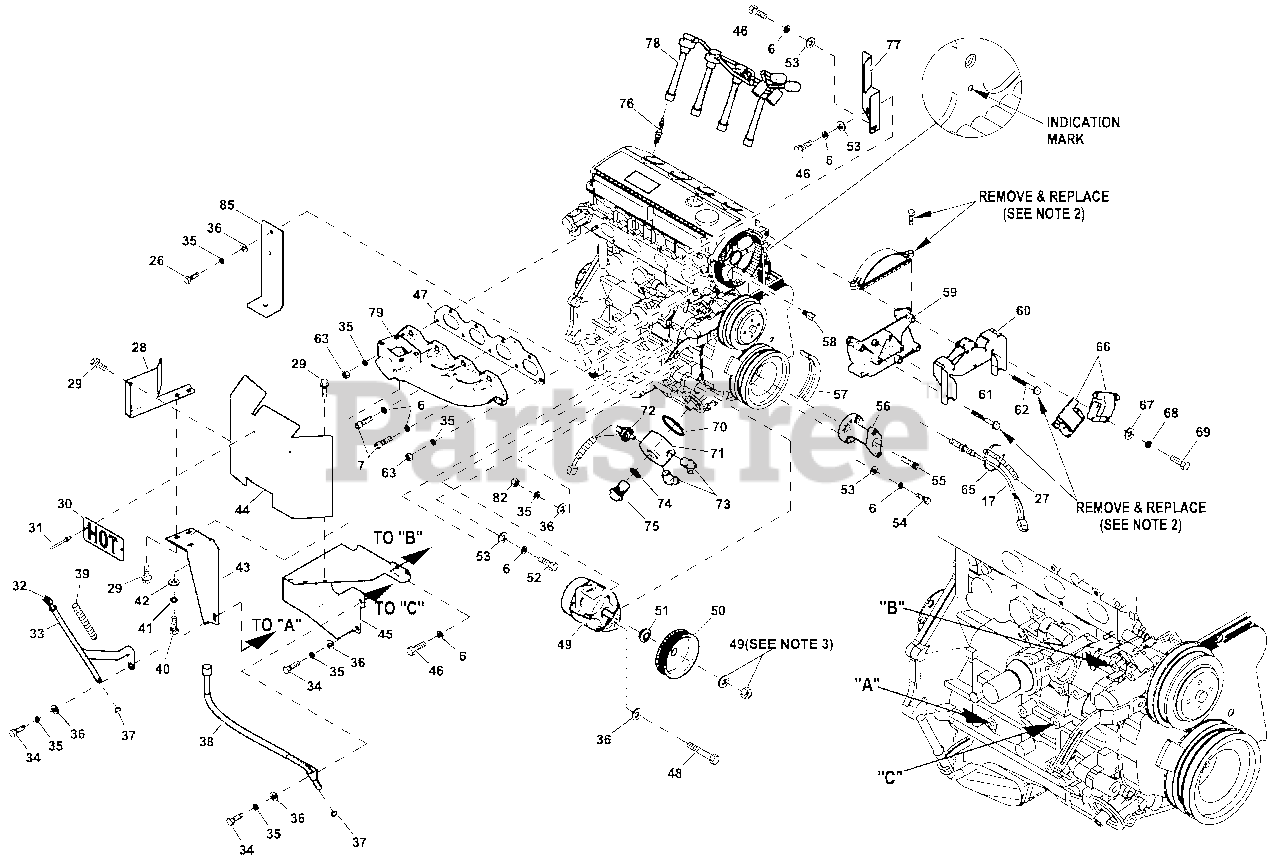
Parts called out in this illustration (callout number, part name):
1	ENGINE 2.4LG2 CERTIFIED
2	CLAMP HOSE #6 .43-.78
3	HOSE 5/16 ID TYP1SNGL HTR
4	GASKET INTAKE MANIFOLD G2
5	MANIFOLD INTAKE (MACHINED)
6	WASHER LOCK M8-5/16
7	SCREW SHC M8 -1.25 X 25
8	TEMPERATURE SENDER, DELPHI
9	PLUG STD PIPE 1/4 STEEL SQ HD
10	NUT HEX M8-1.25 G8 CLEAR ZINC
11	WASHER NYLON .565
12	TUBE OIL FITTING ASSEMBLY
13	SCREW HHCM10-1.25X40 C8.8
14	DECAL G2 IMPORT
15	NUT HEX M6-1.0 G8 CLEAR ZINC
16	SCREW SHC M8-1.25 X 30 C12.9
17	MAGNETIC PICKUP
18	MOTOR STARTER
19	SPACER 2.4L G2 FLEX PLATE
20	ADAPTER ENGINE
21	FLEX PLATE 2 POLE 2.4L G2
22	WASHER FLAT .531 ID X 1.062 OD
23	SCREW HHCM12-1.25X 20 C10.9
24	SCREW HHCM10-1.25X45 G8.8
25	WASHER SHAKEPROOF EXT 7/16 STL
26	SCREW HHCM10-1.25X30 G8.8
27	CONDUIT FLEX.25"ID(7.5"LG)
28	SHIELD INNER HEAT 2.4L TURBO
29	SCREW HHTT M6-1.0 X 12 ZINC
30	PLATE "HOT"
31	RIVET POP .125X0.337 STEEL
32	ASSEMBLY DIPSTICK G2.4L
33	ASSY DIPSTICK TUBE 2.4 G2
34	SCREW HHCM10-1.25X 20 C8.8
35	WASHER LOCK M10
36	WASHER FLAT 3/8-M10 ZINC
37	O-RING SIZE 9.0MM X 2.0MM NITR
38	TUBE TURBO OIL RETURN G2 2.4L
39	CONDUIT THERMAL FLEX 13MM ID
40	SCREW HHC M6-1.0 X 16 C8.8
41	WASHER LOCK M6-1/4
42	WASHER FLAT 1/4-M6 ZINC
43	BRACKET EXH MANIFOLD 2.4 TURBO
44	HEAT SHIELD TURBO 2.4L
45	BRACKET HEAT SHIELD 2.4L
46	SCREW HHC M8-1.25X 16 C8.8
47	GASKET EXHAUST MANIFOLD
48	SCREW HHC M10-1.5X 120 C8.8
49	ALTERNATOR DC W/OUT PULLEY
50	PULLEY DC ALTERNATOR
51	SPACER DC ALTERNATOR PULLEY
52	SCREW HHC M8-1.25X 25 G10.9
53	WASHER FLAT 5/16-M8 ZINC
54	SCREW HHC M8-1.25X35 G8.8
55	SCREW SHC M14-1.5X 35 G10.9
56	ADAPTER 2.4L CRANKSHAFT MACH
57	POLY V-BELT G2
58	CAM SENSOR PIN ASSY
59	COVER CAM GEARG2RK
60	BRACKET ASM-2.4L COIL G2
61	SCREW HHC M8-1.25X65 C8.8
62	SCREW HHC M8-1.25X70 G8.8
63	NUT HEX M10-1.25 G 8YELCHR
64	WASHER FLAT M6
65	TIE WRAP UL 7.4"X .19" BLK
66	COIL-2.4LG2 IGNITION
67	WASHER FLAT #10 ZINC
68	WASHER LOCK #10
69	SCREW HHM #10-32X1-1/4
70	O-RING 2.5"X 2.75"X 1/8" VITON
71	ADAPTOR OIL FILTER 2.4L G2
72	HARN LOW OIL PRESS SWITCH A SSY
73	ADAPTOR 45D JIC37 1/2NPT X 3/4
74	O-RING 1 "X 1.25" X 1/8" VITON
75	NUT OIL FILTER ADAPTOR 2.4L G2
76	PLUG SPARK
77	SHIELD HEAT IGNITION COIL 2.4L
78	SPARK PLUG WIRE SET 2.4L G2 IG
79	MANIFOLD EXH 60K G2 TURBO (MA)
81	HARN ENG G2.4L G2 PROTECTOR
82	NUT HEX M10-1.5 G8YEL CHR
83	SUPPORT LH ENGINE 2.4L
84	SPACER LH ENGINE MOUNT
85	SUPPORT RH ENGINE 2.4L
